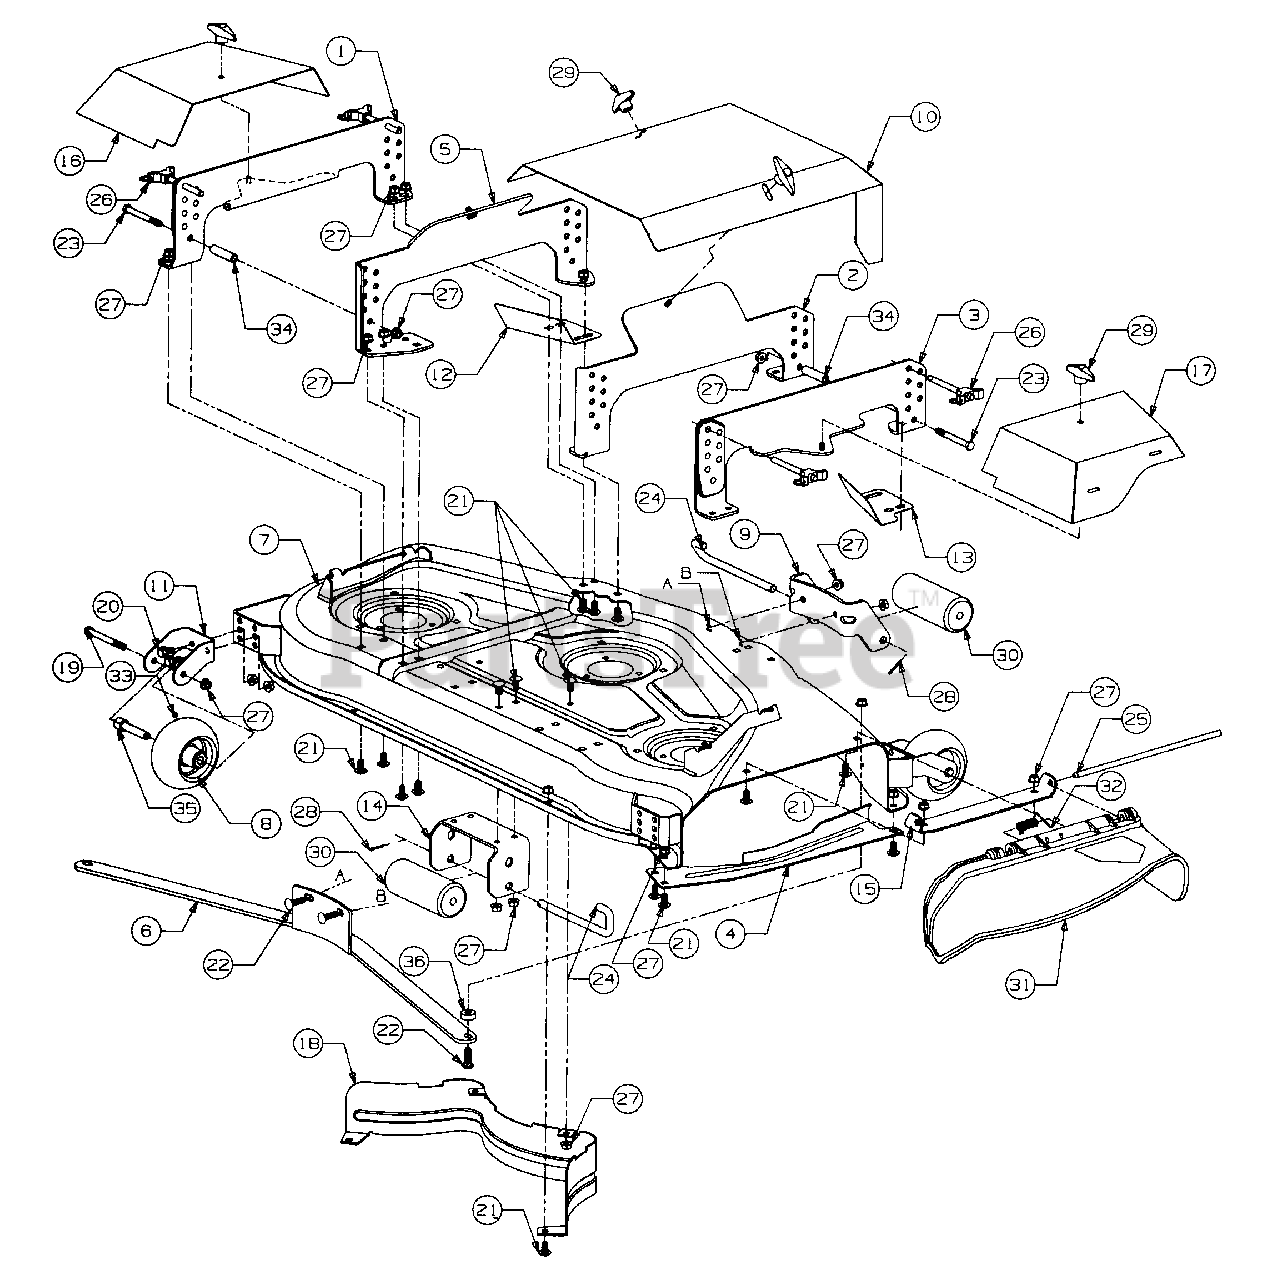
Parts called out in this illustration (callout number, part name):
5	Hanger, LH Inner
8	Wheel, Deck, 5" Dia w/Fitting
13	Plate, RH Filler
20	Screw, Hex Wash Sf Tap, 3/8-16 X .75 Lg
21	Bolt, Sht Nk Carriage, 3/8-16 X .75 Lg GR5
22	Bolt, Carriage, 3/8-16 X 1.25 Lg GR5
23	Screw, Hex Cap, 3/8-16 X 3.25 Lg GR5
24	Pin, Roller, 1/2 Dia X 7.31 Lg
25	Washer, Special
25	Pin, Hinge, .375 Dia X 12.55 Lg
26	Pin, Quick Release, 3/8 Dia
27	Nut, Hex Flanged Lock, 3/8-16
28	Pin, Cotter, 1/8 Dia X 1.0 Lg
29	Knob, Wing Nut
31	Deflector, Chute
32	Spring, Torsion
33	Fitting, Lube, 3/16 Drive
34	Spacer, Deck Hanger
35	Spacer, Deck Wheel
36	Spacer, Front Bar
